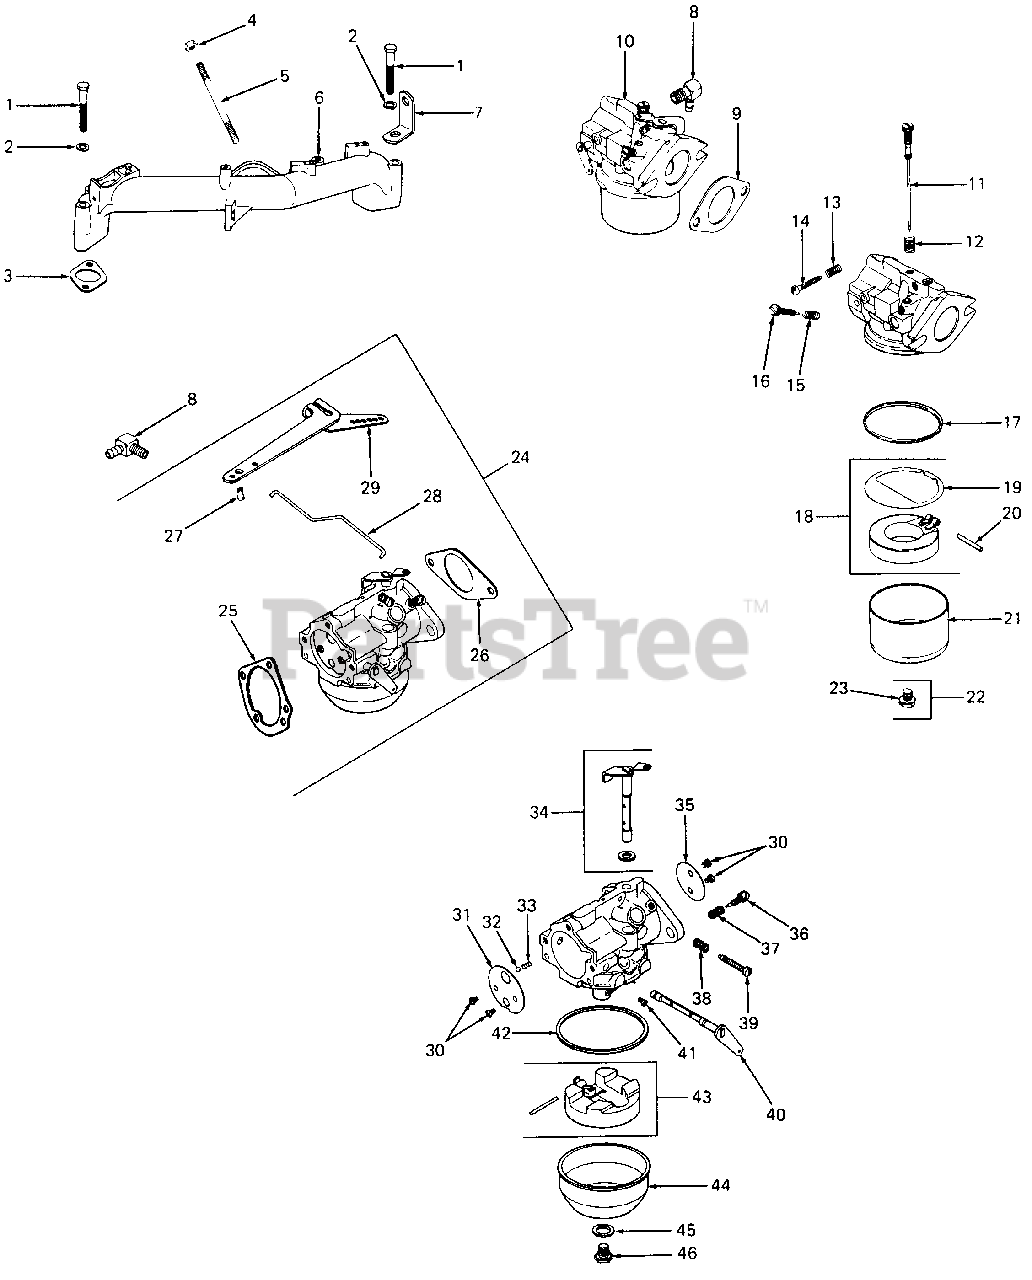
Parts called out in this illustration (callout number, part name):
1	Screw, H.C., 5/16-18 X 2.75 Lg
2	Washer, Lock, 5/16
3	Gasket, Intake Manifold
4	Nut, Hex Jam, 5/16-18
5	Stud, 5/16-18 X 1.0 Lg
6	Manifold, Intake
7	Strap, Lifting
8	Connector, 90
9	Gasket, Carburetor
10	Carburetor Assembly
11	Needle, Main Fuel
12	Spring, Main Fuel
13	Spring, Idle Speed
14	Screw, Idle Speed Adj
15	Spring, Idle Fuel
16	Needle, Idle Fuel Adj
17	Gasket, Bowl
18	Kit, Float
19	Gasket, Bowl Baffle
20	Pin, Float Hinge
21	Bowl, Fuel
22	Screw, Bowl Retainer
23	Gasket, Bowl Retainer Screw
24	Kit, Carburetor w/Linkage
25	Gasket, Elbow
26	Gasket, Carburetor
27	Bushing, Linkage Retaining
28	Linkage, Governor
29	Arm, Governor
30	Screw, Throttle & Choke Plate
31	Plate, Choke
32	Ball, Choke Friction
33	Spring, Choke Friction
34	Shaft, Throttle w/Lever & Seal
35	Plate, Throttle
36	Needle, Idle Fuel Adj
37	Spring, Idle Fuel
38	Spring, Idle Speed
39	Screw, Idle Speed Adj
40	Lever, Choke
41	Jet, Main
42	Gasket, Bowl
43	Kit, Float
44	Bowl, Fuel
45	Gasket, Bowl Retainer Screw
46	Screw, Bowl Retainer
